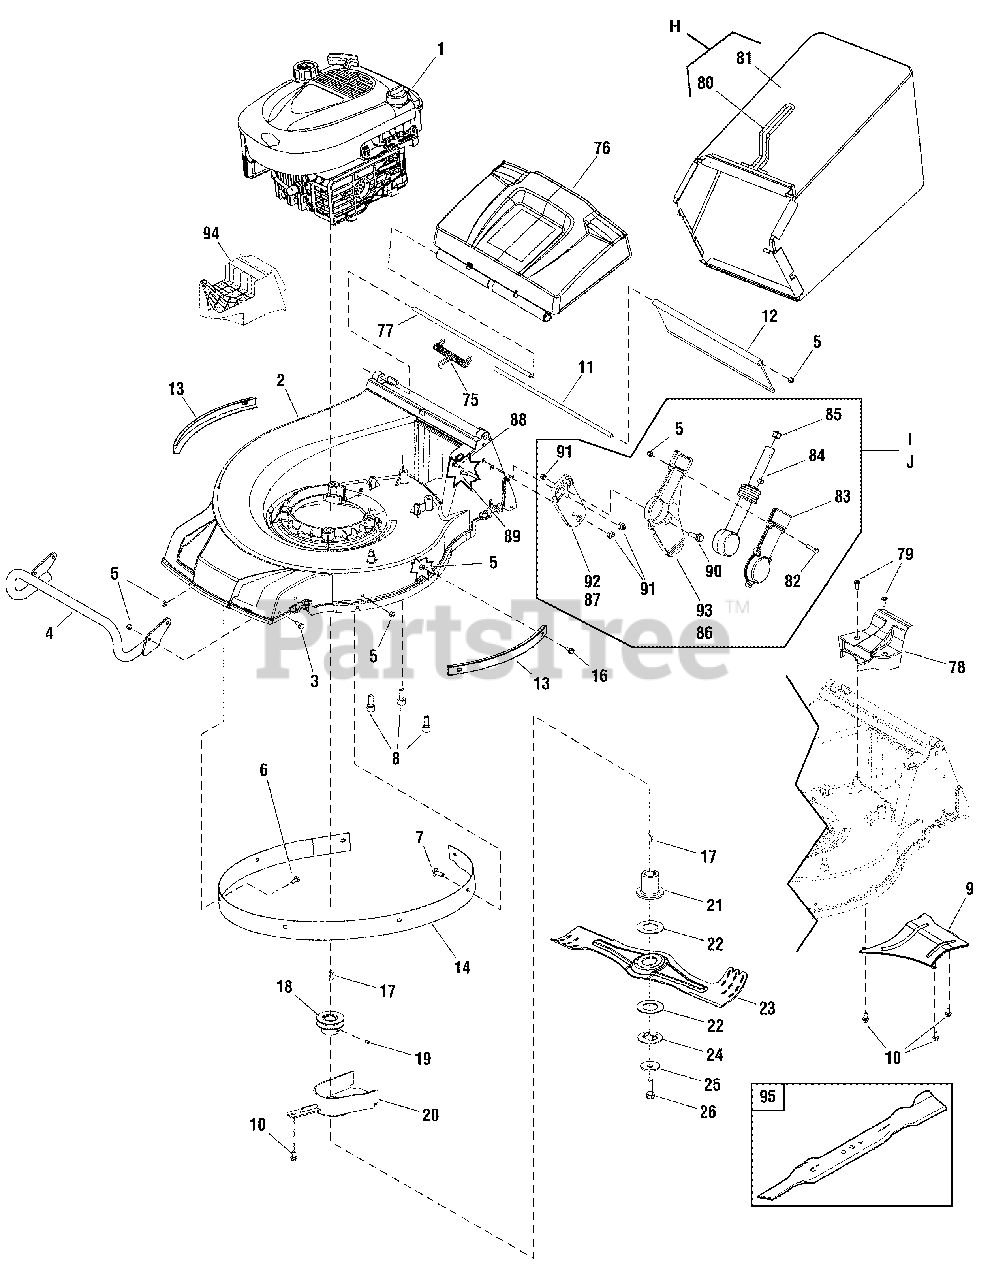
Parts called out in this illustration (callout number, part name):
1	* ENGINE, 850 Series, Briggs & Stratton
2	DECK, 19"
2	DECK, 21"
3	BOLT, Hex Flange
4	BUMPER, 19"
4	BUMPER, 21"
5	NUT, Hex, Nylon Insert, Torque Type
6	SCREW, Truss Head, Cross Recessed
7	SCREW, Truss Head, Cross Recessed
8	SCREW, Inner Hexagon, Round Head, Tapping
9	DEFLECTOR, Lower
10	SCREW, Hex Flange, Tapping
11	SHAFT, Rear Deflector
12	DEFLECTOR, Rear
13	SHIELD, Outer
14	SHIELD, Inner Ring
16	BOLT, Hex Flange
17	KEY, Woodruff
18	PULLEY, Engine
19	SCREW, Inner Hexagon Recessed
20	SHIELD, Lower Belt
21	ADAPTOR, Blade
22	DISC, Friction
23	BLADE, 19"
23	BLADE, 21"
24	CLIP
25	SPRING, Dishing
26	BOLT, Blade
75	SPRING, Torsion
76	COVER, Rear
77	SHAFT, Rear Cover
78	SHIELD, Upper Pulley
79	SCREW, Inner Hexagon Tapping
80	FRAME, Grass Catcher, 19" Deck
80	FRAME, Grass Catcher, 21" Deck
81	BAG, Grass Catcher, 19" Deck
81	BAG, Grass Catcher, 21" Deck
82	BOLT, Hexangular, Full Thread
83	COVER, Bracket
84	AVS ASSEMBLY
85	AVS PLUG
86	BRACKET, Handle, RH
87	BASE, Bracket, RH
88	BOLT, Carriage
89	BOLT, Carriage
90	BOLT, Hex Flange
91	NUT, Nylon Insert, Torque Type
92	BASE, Bracket, LH
93	BRACKET, Handle, LH
94	PLUG, Mulch, 19"
94	PLUG, Mulch, 21"
95	BLADE, Mulching, 19"
95	BLADE, Mulching, 21"
H	GRASS CATCHER ASSEMBLY
I	BRACKET ASSEMBLY, RH
J	BRACKET ASSEMBLY, LH
